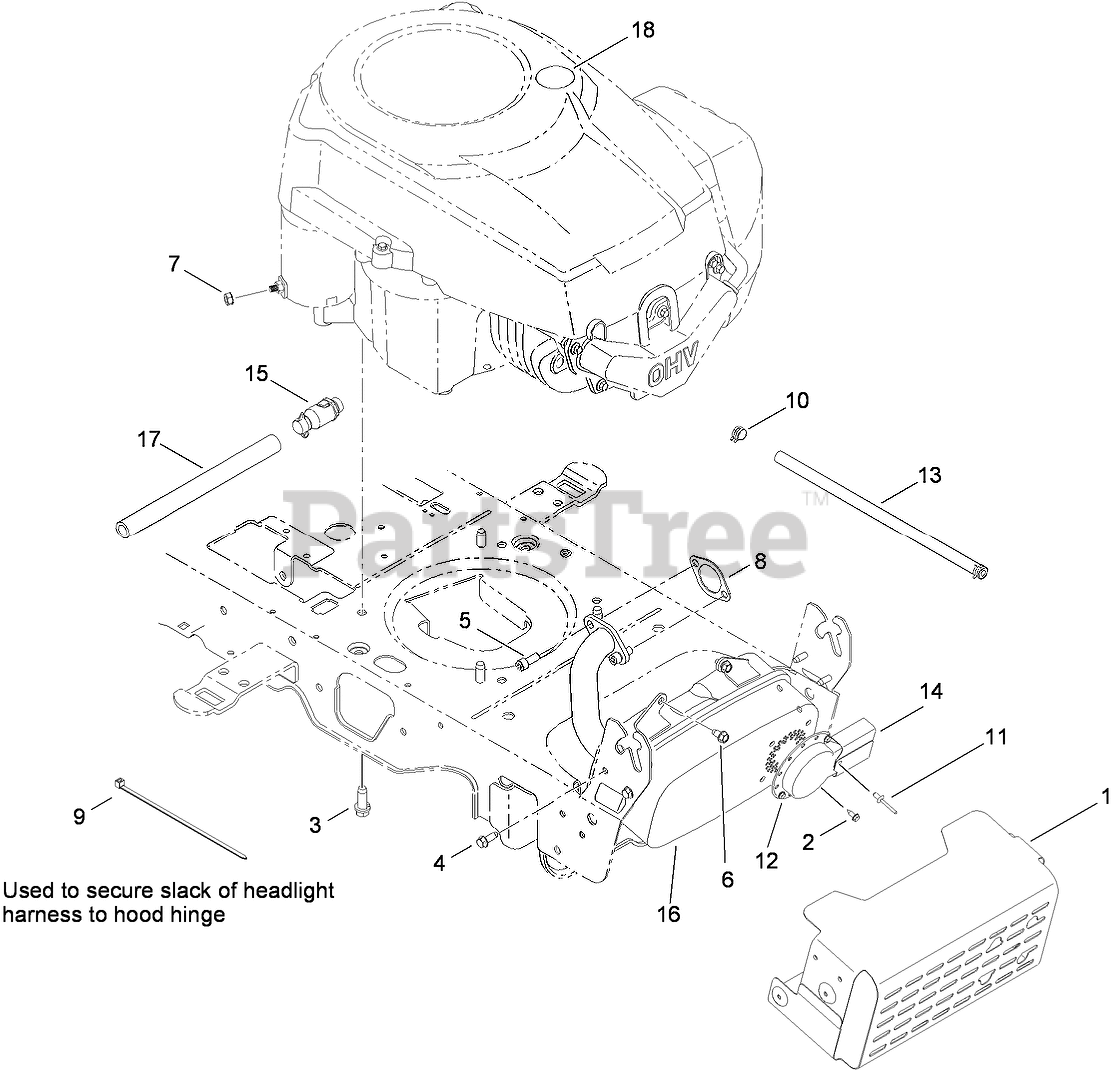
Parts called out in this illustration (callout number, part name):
1	SHIELD-MUFFLER
2	SCREW-HWHTF
3	SCREW-HH, TAP
4	SCREW-HWHTF
5	SCREW-HSH
6	SCREW-HWH
7	NUT-SEMS
8	GASKET-EXHAUST
9	TIE-CABLE
10	CLAMP-HOSE
11	RIVET-POP
12	DEFLECTOR-MUFFLER
13	HOSE-FUEL
14	DEFLECTOR-MUFFLER, LONG
15	Drain-Oil
16	MUFFLER
17	HOSE-DRAIN
18	DECAL-CHECK OIL
